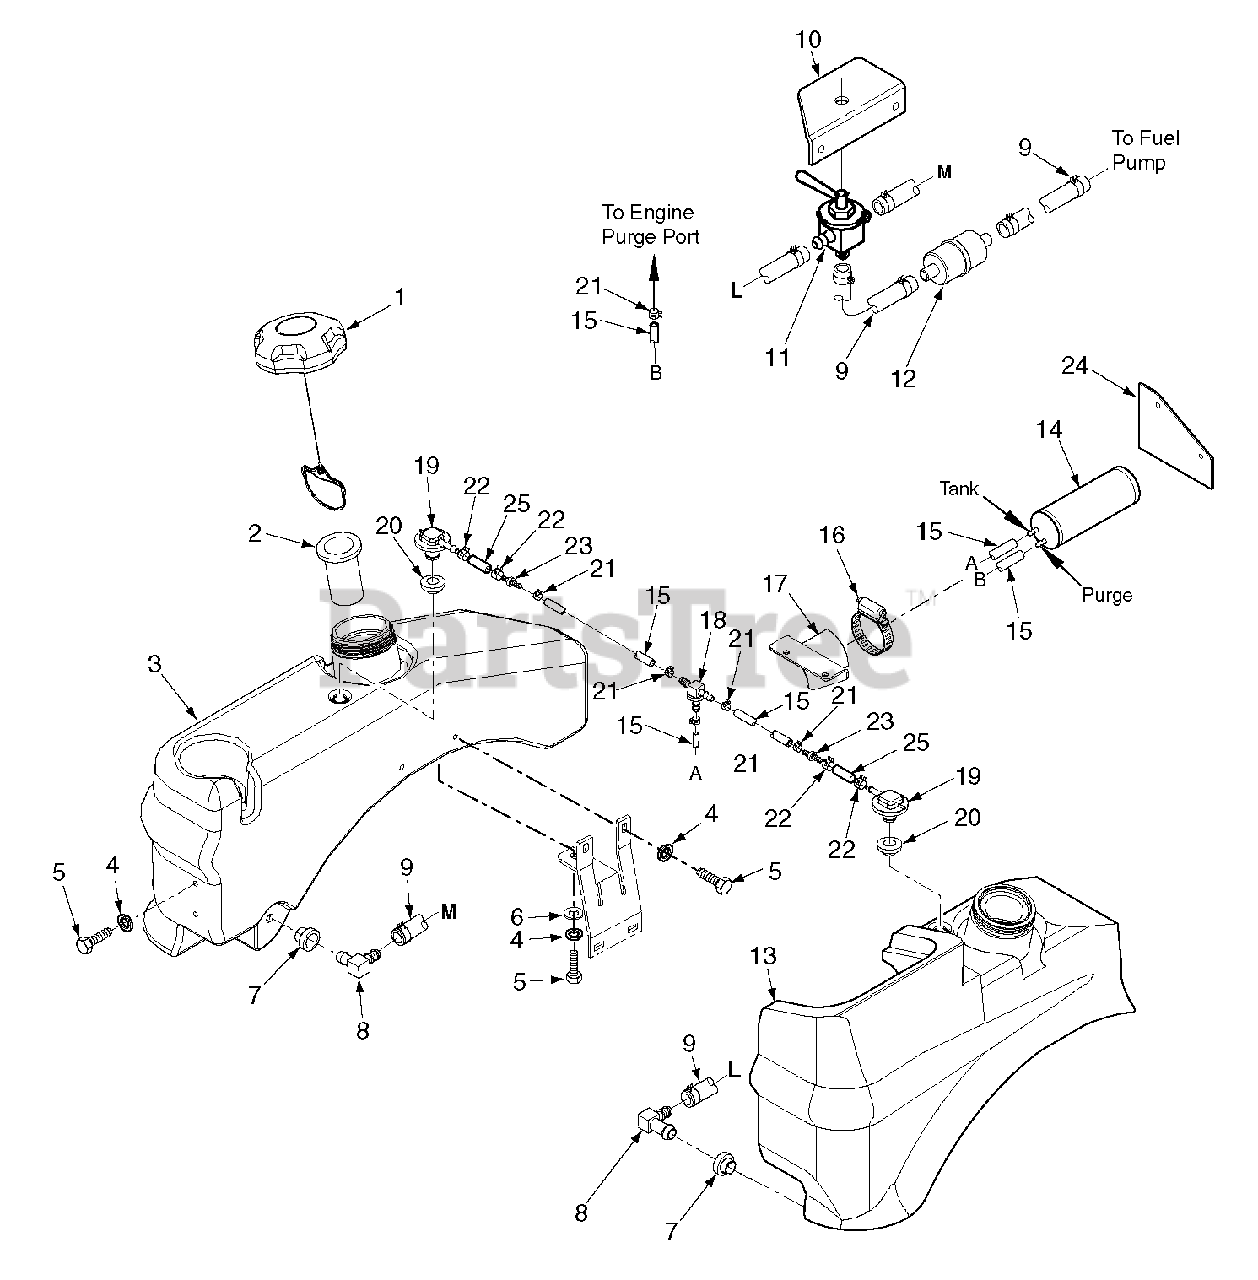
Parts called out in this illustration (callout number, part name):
1	Fuel Cap w/ Tethered
2	Tube, Fuel Tank Insert
3	Fuel Tank RH
4	Lockwasher, 5/16" Spring
5	Bolt, Hex Head 5/16-18 x 3/4"
6	Flatwasher, 5/16-.375 x .875 x .083
7	Tank Bushing
8	Fitting, 90 Degree
9	Fuel Hose, 1/4" I.D. Non-Perm
10	Bracket, Fuel Valve
11	Fuel Shutoff Valve
12	Fuel Filter
13	Fuel Tank LH
14	Carbon Canister
15	Hose, 3/16"
17	Bracket, Canister Mounting
18	T - Fitting, Fuel Vent
19	Valve, Rollover
20	Grommet, Viton
21	Clamp, Vapor Recovery Hose 3/16"
22	Clamp, Fuel Hose
23	Mender, 1/4 x 3/16 w/.02 Hole
24	Heatshield
25	Hose, 1/4" Vapor Recovery
